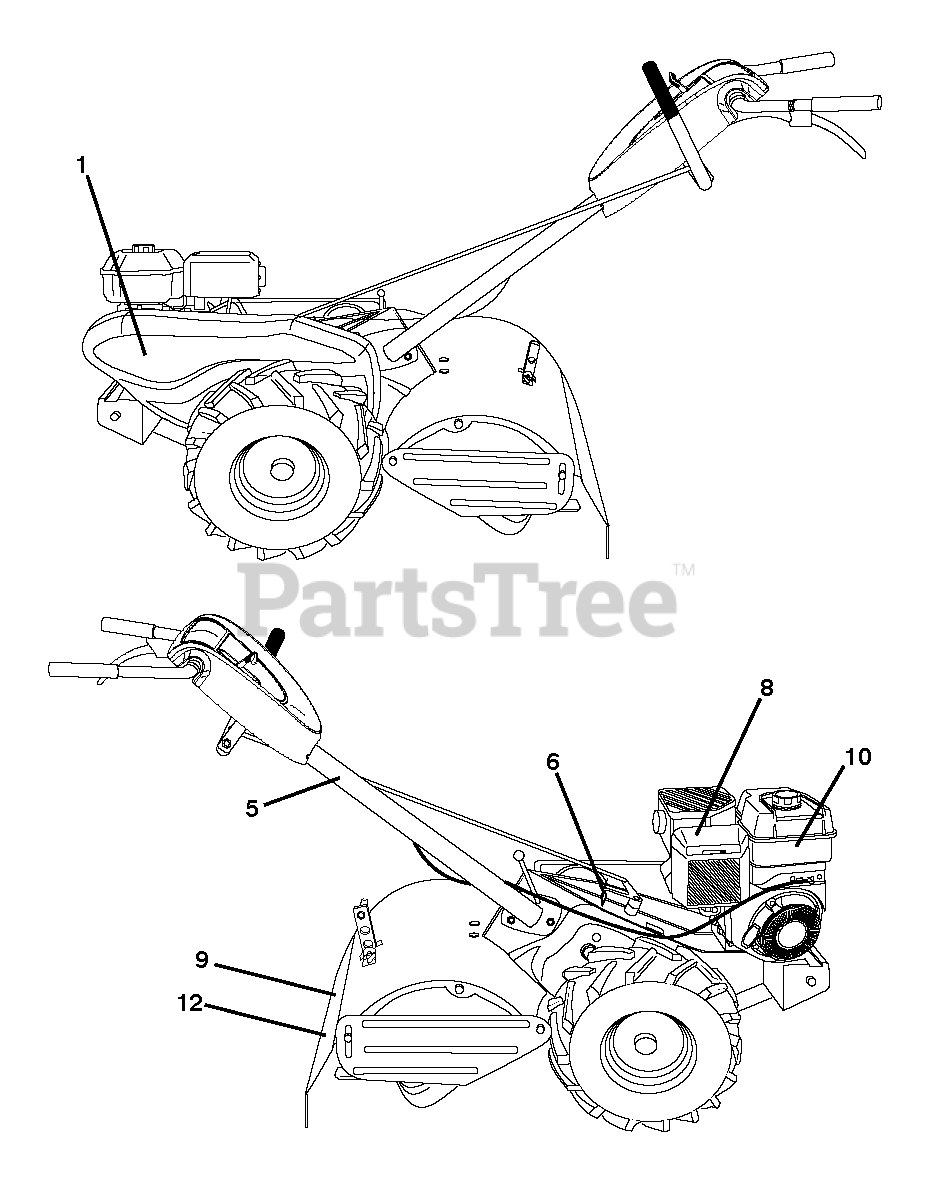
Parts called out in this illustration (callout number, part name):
6	DECAL.SHIFT.INDICATOR.TILLER
9	DECAL EUROPE STANDARD CE
10	DECAL.B&S.900.TANK.REF.276991
